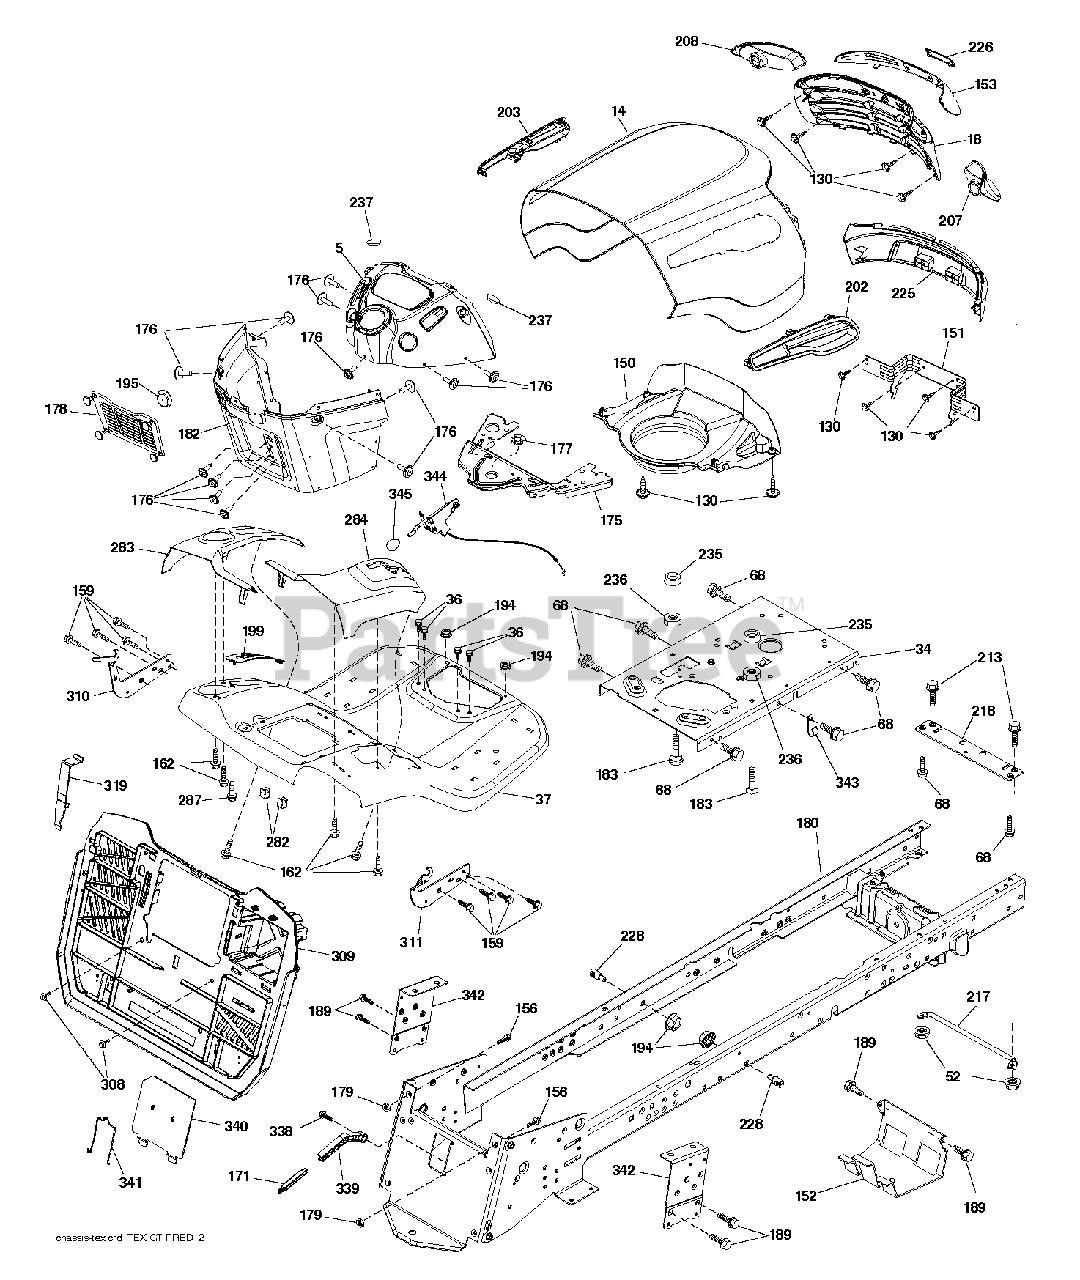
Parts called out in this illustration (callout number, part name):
14	HOOD.PNT.PREDATOR.YT/GT.667
18	GRILLE.SVC.PREDATOR.YT.TEX
36	SCREW 5/16"
37	Fender, TEX SRD CRD Front Guards
52	LOCKNUT
130	SCREW.#10 X 0.750.BOS THREAD
150	AIR.DUCT.HOOD.PREDATOR.NO.RING
151	Pivot Predator Bracket
152	SHIELD BROWNING
153	LENS.BAR.PREDATOR.YT.CLEAR
156	BOLT
159	SCREW, 3/8-16X3/4
162	SCREW.HI-LO.CONSOLE
171	EXTENSION.BAGGER.FULL.
175	PLATE.CROSSMEMBER.HUSQ
176	SCREW.#10-24X5/8.RN.QU
177	BUSHING,STEERING
178	CARGO.ASM.NET.TXGT.W/C
182	DASH DASH LOWER
183	BOLT.5/16-18X1-1/4 FULL THD
189	SCREW
194	NUT LOCK HEX FLANGE 5/16-18
195	PLUG.HOLE.DASH.LOWER.12V.BLK
213	BOLT
217	ROD.PIVOT.HOOD
218	X-PIECE.HOOD.STOP.NON/
225	BUMPER.GRILLE.PREDATOR.YT.667
226	LOGO.PREDATOR GT.TEX.BLACK
228	STUD.FASTNER.W/ANTI-ROTATE
235	SPACER FENDER
236	NUT.CENTERLOCK.5/16-
237	PLUG.MOUNT.CARGO.BLK
282	CLIP.RETAINER.CONSOLE.LT.HUSQ
283	CONSOLE.DECKLIFT.LH.SRD.TEXCRD
284	CONSL.SHFT.PEDAL.RH.SRD.TEXCRD
308	BOLT, 5/16-18 X 1 3/4
310	LH.ADJUST.HANGER.BRACKET.ASM
311	RH.ADJUST.HANGER.BRACKET.ASM
319	BRACKET.ACTUATOR.BAGGER.SRD
338	BOLT BOLT SHOULDER
339	LEVER.BAGGER.FULL.TEX.
340	DOOR.PNT.BATTERY.TRY.TEX.CRD.
341	LATCH
342	SUPPORT SUPPORT FENDE
343	Clip
344	CONTROL.EZ.MULCH.TEX/CRD
345	Shift Knob
